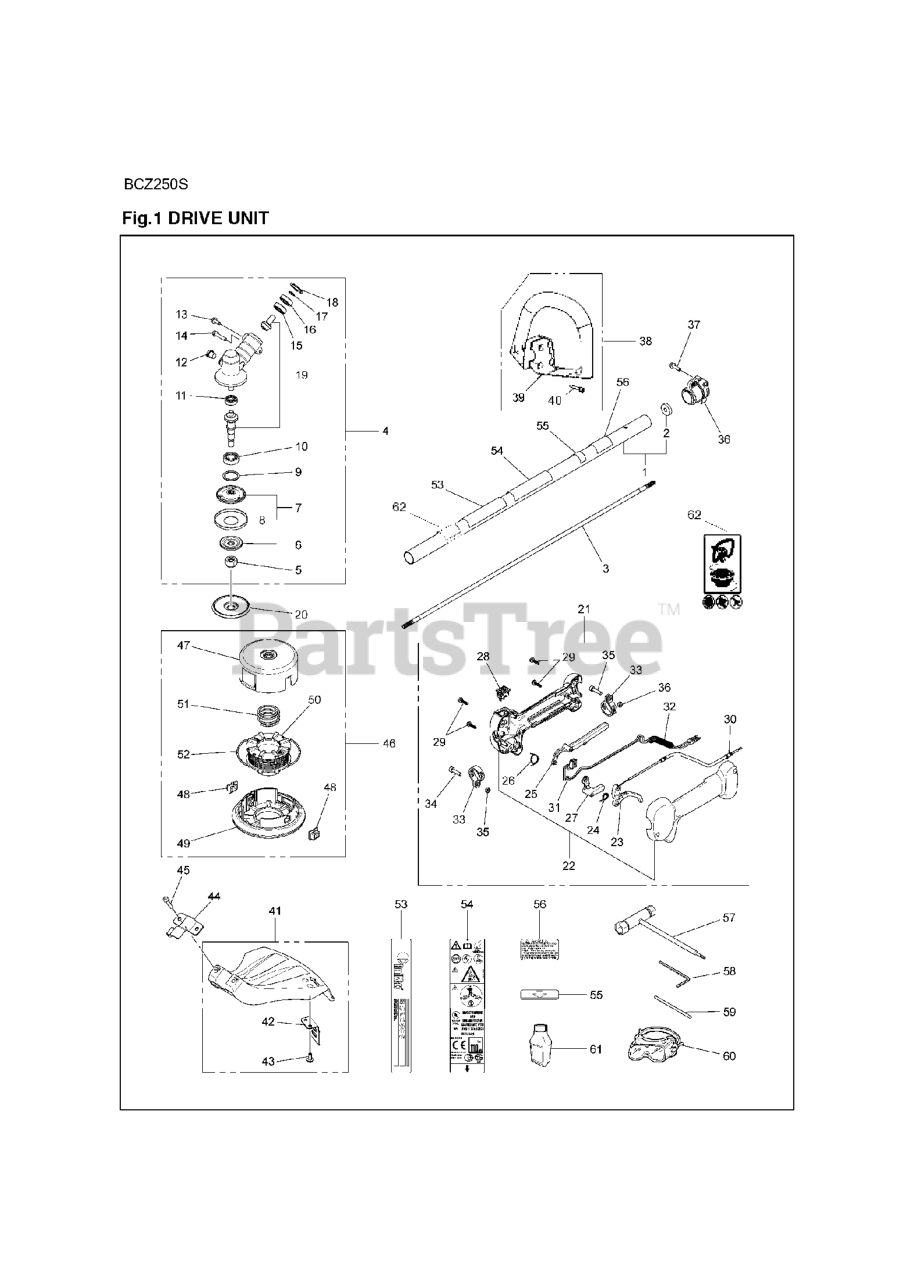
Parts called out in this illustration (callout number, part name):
1	TUBE
3	DRIVESHAFT
4	GEAR HEAD
5	GEARHEAD NUT - BRUSHCUTTER
6	SUPPORT FLANGE
7	DRIVE DISC
8	WASHER
9	RETAINING RING SGH 28
11	BALL BEARING 8X22X7/608Z
12	PLUG
15	BALL BEARING 24X9X1/609ZR
17	RETAINING RING
18	RETAINING RING
21	ASSY THROTTLE
22	GRIP HALF SET
23	LEVER, THROTTLE
24	SPRING, THROTTLE
25	LEVER, SAFETY
27	LEVER JOINT
28	STOP SWITCH NM_09091801
31	CORD - C
35	NUT
36	HANGER COMP
38	HANDLE ASSY. (RPLS T319514001)
39	HANDLE T
41	GUARD ASSY
44	BRACKET SHIELD
45	BOLT, TORX
46	TAP HEAD RPLS T318915100/02
47	CASE (RPL T318915112)
49	COVER (RPLS T318915131)
50	HOLDER, CORD (RPLS T318915141)
52	CORD
53	DECAL NAME BCZ250S
54	DECAL WARNING
56	DECAL SPARK ARRESTOR WARNING
57	COMBINATION WRENCH TORX
58	L-SPANNER
59	LOCKING PIN
60	GOGGLExxx (RPLS
61	OIL 2 CYCLE ENGINE OIL 2.
62	DECAL WARNING "NO BLADES"
